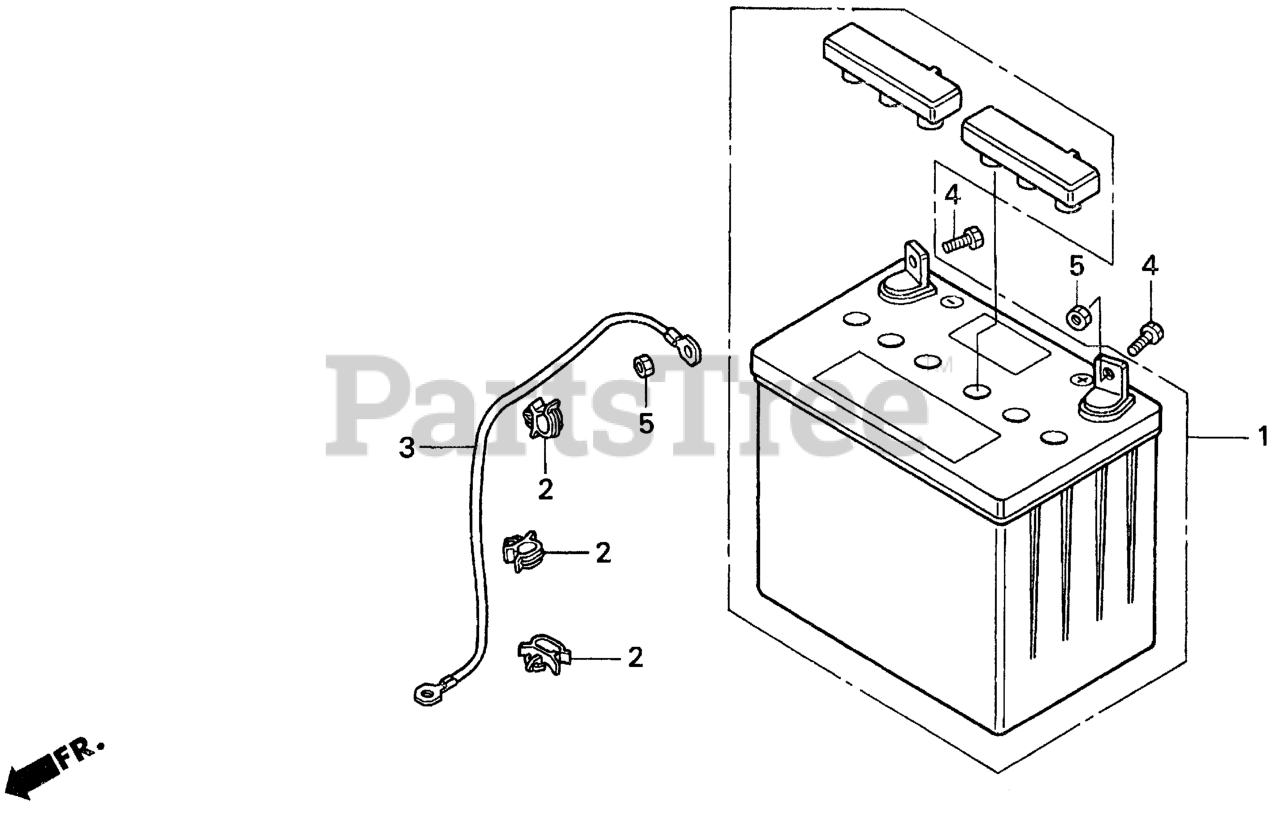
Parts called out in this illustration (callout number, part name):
1	BATTERY ASSY. (U1L)
2	CLIP, WIRE HARNESS
3	CABLE ASSY., GROUND
4	BOLT, BATTERY TERMINAL
5	NUT, BATTERY TERMINAL
